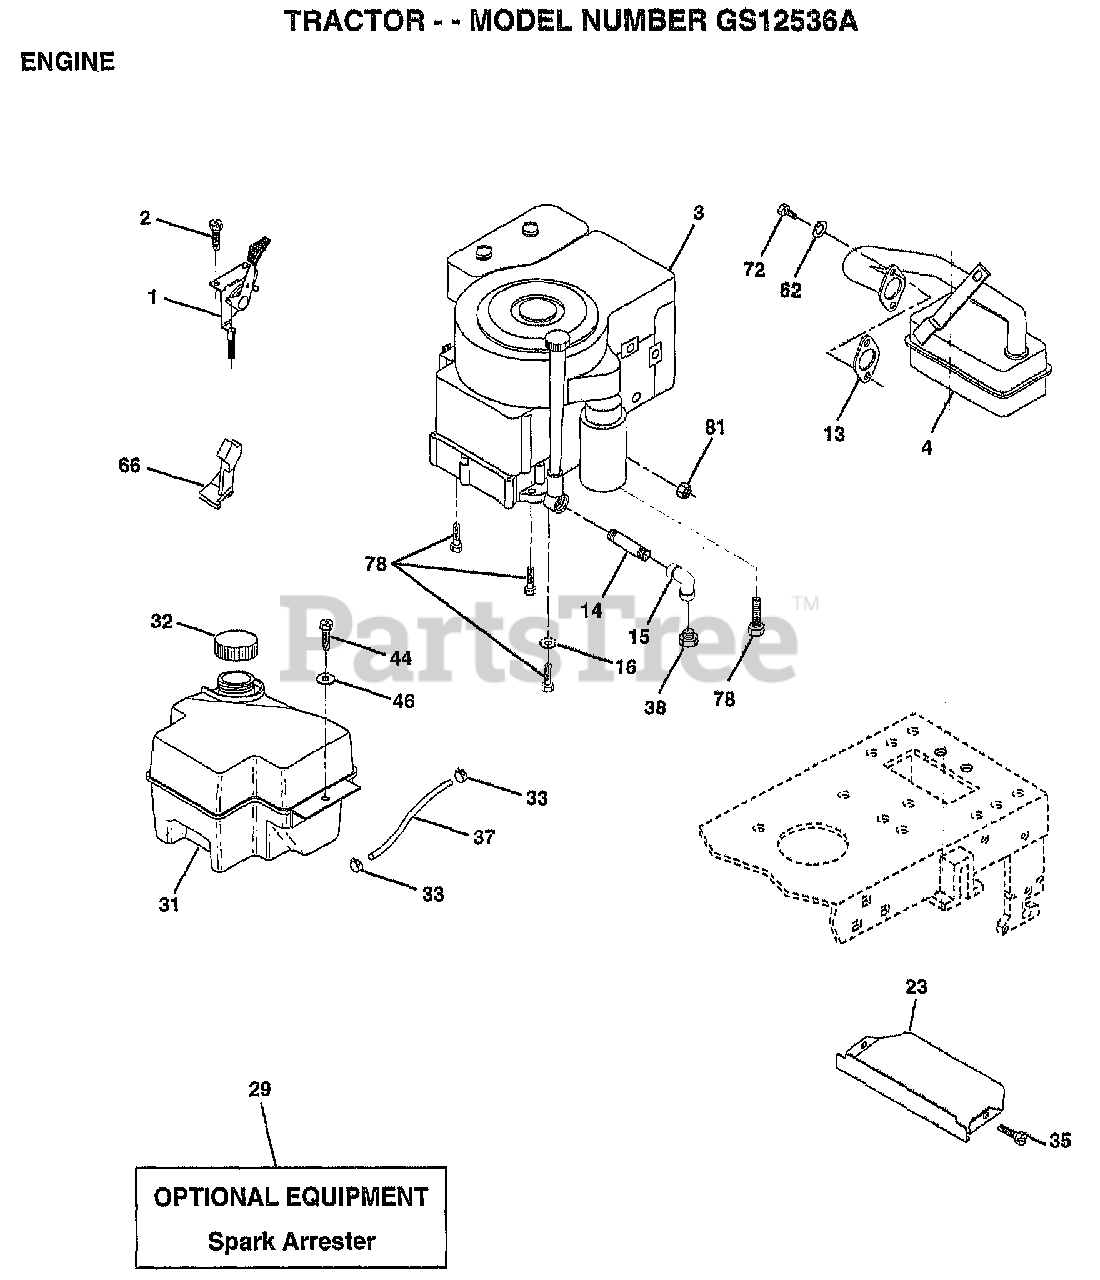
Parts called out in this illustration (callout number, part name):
1	CONTROL.THTL.23.5
2	SCREW LT
4	MUFFLER
14	PIPE NIPPLE
15	ELBOW
16	LOCKWASHER
23	SHIELD.BRN/DBR.GD
31	TANK.FUEL.FRONT.
32	CAP ASM FUEL
33	HOSE CLAMP
35	SCREW
37	LINE FUEL
44	SCREW HEX CRT
46	WASHER
62	LOCKWASHER
66	"STOP,DASH THROTT"
72	SCREW
78	SCREW
81	NUT
